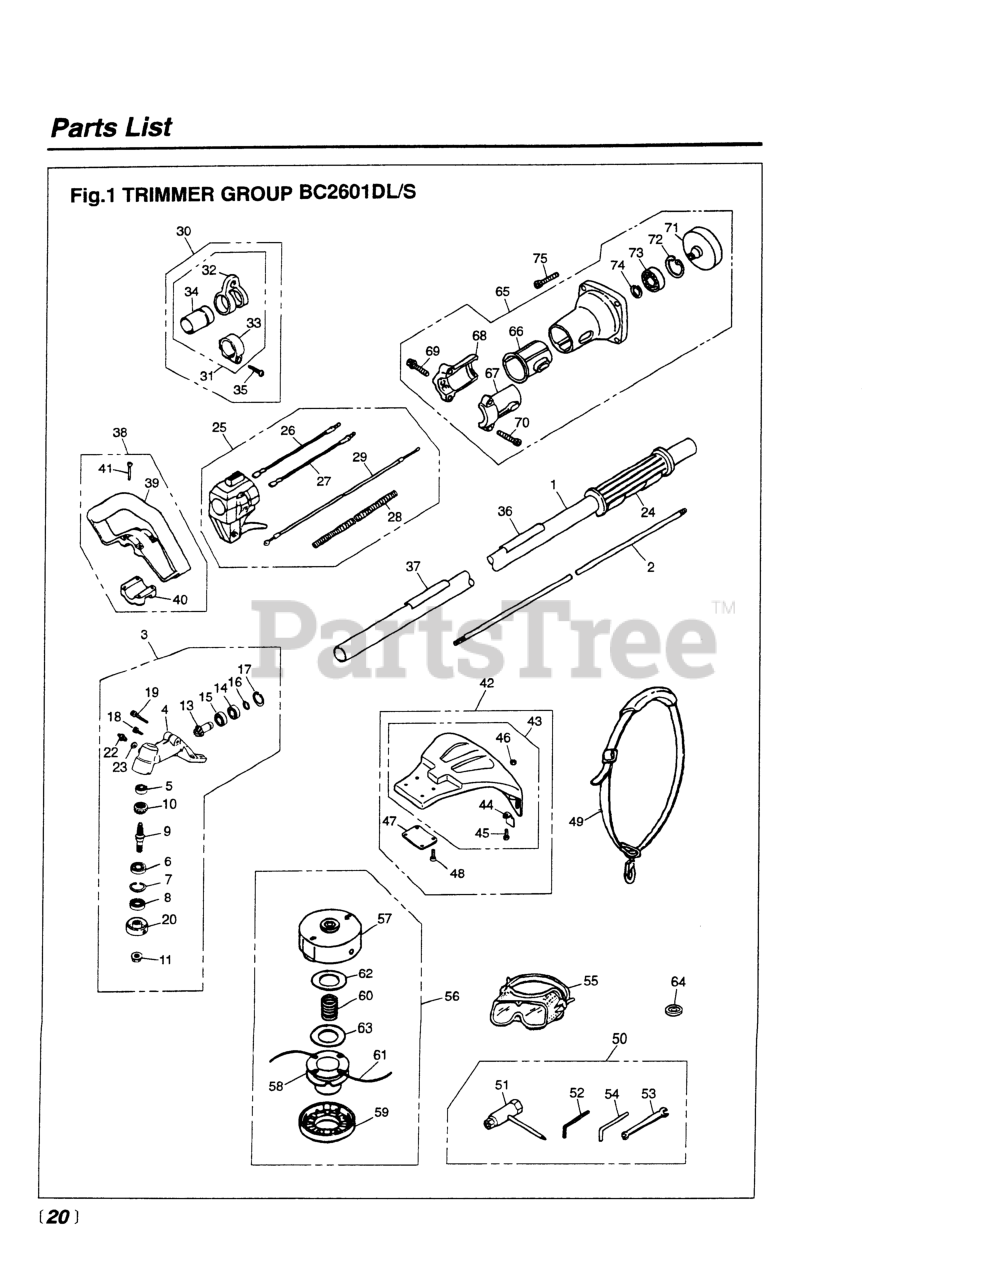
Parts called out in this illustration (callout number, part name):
3	GEARCASE ASSY (RPLS -13000)
4	GEARCASE
5	BEARING (RPLS T3300-13521)
6	BEARING (RPLS T3403-13510)
7	RING, SNAP, M26 X 1.2
8	SEAL, OIL
9	SHAFT
10	GEAR
11	NUT
13	PINION
14	BEARING (RPLS T3300-13531)
15	BEARING (RPLS T3403-13530)
16	RING, SNAP (RPLS T3300-13330)
17	RING, SNAP, M24 x 1.2
18	BOLT, M5 X 10
19	BOLT
20	HOLDER (A)
22	FITTING, GREASE
23	WASHER, M6 X .8
24	GRIP (RPLS 3577-32140 & 3220-
26	CORD (A), BLACK
27	CORD (B), RED
28	TUBE (RPLS 4900-72141)
29	CABLE (RPLS 5580-83100)
30	HANGER ASSEMBLY
31	HANGER COMPLETE
32	HANGER
33	CLAMP
34	SLEEVE
36	LABEL (BC2601DL)
37	PLATE, CAUTION
38	HANDLE ASSEMBLY
39	HANDLE
42	GUARD ASSY (RPLS -24000)
43	GUARD COMP (RPLS. -24100)
44	BLADE (RPLS T3002-24120)
46	NUT
47	PLATE
48	BOLT (USE 3310-31720)
52	WRENCH (TOOL)
53	SPANNER, 8 X 10 (RPLS 2540- )
54	BAR
55	GOGGLE
56	4
57	CASE (RPLS -15112)
58	HOLDER, CORD (RPLS -15141)
59	COVER (RPLS -15130)
60	SPRING (RPLS -99161)
61	CORD
62	PLATE, LARGE
63	PLATE, SMALL
64	HOLDER (B)
66	CUSHION
67	BRACKET (A) (RPLS -31210)
68	BRACKET (B) (REPLACES -31220)
69	BOLT (USE 3310-31720)
70	BOLT, M5 X 30
72	RING, SNAP, M28 x 1.2
73	BEARING
74	RING, SNAP (RPLS 3130-13270)
75	BOLT, M6 x 20
